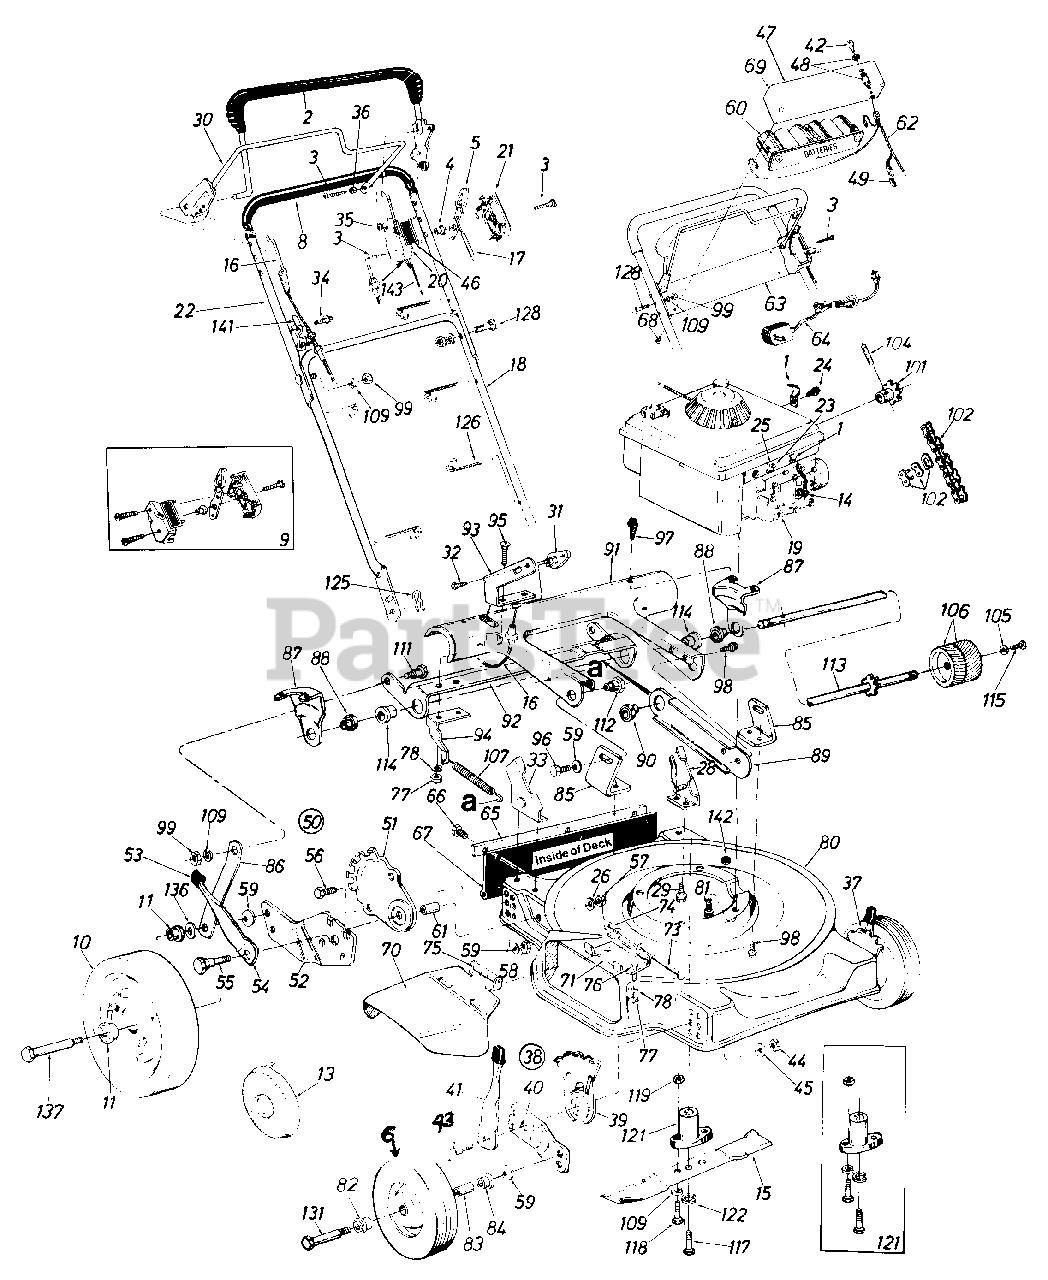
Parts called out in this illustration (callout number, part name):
1	Casing Clamp
2	Control Handle Ass'y.-L.H.
3	Truss Mach. Hi-B Tap Scr. #12 x 1.5"
4	Control Disc Pin
5	Throttle Control Lever
6	Front Wheel Ass'y. Comp.
9	Control Housing Comp.
10	Rear Wheel Ass'y. Comp.
11	Fl. Ball Brg 1/2" 1 D.
13	Hub Cap
14	Spark Plug Insulator
15	22" Blade
16	Clutch Cable w/Spring-33"
17	Throttle Wire-53"
18	Lower Handle
19	Engine
20	Clutch Panel Half
21	Control Panel Haif
22	Upper Handle
23	Hex B-Tap Scr. #10 x .62"
24	Hex B-Tap Scr. #10 x .38"
25	Casing Clamp
26	Bell-Wash. 5/16" I.D.
28	Handle Brkt. Ass'y-L.H.
29	Hex B-Tap Scr. 5/16-18 x .5"
30	S.P. Bail Ass'y.
31	Barrel Cable Hold-Down R.H.
32	B-Tap Scr. #10 x .44 Lg.
33	Handle Brkt. Ass'y-R.H.
34	Hex Wash. AB-Tap Scr. 5/16 x .75"
35	Spr-Wash. .206 I.D. x .448
36	Spacer .23 I.D. x .30 O.D.
37	Front Height Adj. Ass'y.-L.H.
38	Front Height Adj. Ass'y.-R.H.
39	Height Adj. Plate
40	Pivot Bar
41	Spring Lever Ass'y. w/Knob
42	Ignition Key
43	Shld. Bolt .50 Dia. x .430
44	Hex Nut 3/8-16 Thd.
45	Bell-Wash. .39 I.D. x 1.38 O.D.
46	Control Label
47	Instruction Label
48	Ignition Switch
49	Plug
50	Rear Height Adj. Ass'y.-R.H.
51	Index Plate
52	Pivot Bar-R.H.
53	Spring Lever Knob
54	Spring Lever
55	Shld. Bolt .50 Dia. x .433
56	Hex Bolt 3/8-16 x .75
57	Hex Cent. L-Nut 5/16-18 Thd.
58	Hex Nut 3/8-16 Thd.
59	Bell-Wash. .40 I.D. x .88 O.D
60	Battery Pack
61	Spacer .383 I.D. x .503 O.D.
62	Wire Harness
63	Lower Battery Tray
64	Battery Charger
65	Retaining Strip
66	Hex AB-Tap Scr. 1/4 x .62
67	Rear Flap Ass'y.
68	Truss Mach. Hi-Riser Tap Scr. 1" Lg.
69	Battery Tray
70	Chute Deflector Ass'y.
71	Adapter Plate
73	Pivot Pin
74	Push Nut 1/4"
75	Torsion Spring
76	Hex Bolt 1/4-20 x .50 Lg.*
77	Hex Nut 1/4-20 Thd.
78	L-Wash. 1/4 I.D.
80	22" Deck Ass'y
81	Hex TT-Tap Scr. 3/8-16 x 1.0
82	Ball Bearing 3/8" I.D.
83	Spacer
84	Ball Bearing 1/2" I.D.
85	Pivot Brkt.
86	Link
87	Axle Brkt.
88	Fl. Ball Brg. 1/2" I.D.
89	Brg. Support
90	Fl. Ball Brg. 1/2" I.D.
91	Pinion-Pivot Cover
92	Drive Engagement Cam
93	Engagement Arm-L.H.
94	Spring Bracket
95	Carriage Bolt lh-20 x .62
96	Hex Bolt 3/8-16 x .50 Lg.
97	Hex AB-Tap Scr. 1/4 x .62
98	Hex AB-Tap 1/4 x .62"
99	Hex Nut 5/16-18 Thd.
101	1OT Sprocket Ass'y.
102	#48 Chain 1/2" Pitch 50 Links
104	Spring Pin Spir. 3/16 Dia. x 1.0
105	Bell-Wash..265" I.D.
106	Drive Pinion Half
107	Extension Spring 4.25 Lg.
109	L-Wash. 5/16 I.D.
111	Shld. Bolt .437 Dia. x .162
112	Shld. Nut .625 Dia. x .165
113	Pinion Shaft w/7T Sprocket
114	Fl. Ball Brg. .501 I.D. H.D.
115	Hex TT-Tap Scr. 1/4-20 x .501' Lg.
117	Hex Bolt 3/8-24 x 2.25
118	Hex Bolt 5/16-24 x 1.0-Spec.
119	Hex Nut 5/16-24 Thd.
121	Blade Adapter Kit
122	L-Wash. 3/8 I.D.-H.D.
125	Intern. Cot. Pin 5/16 Dia.
126	Cable Tie
128	Curved Carriage Bolt 5/16-18 x 1.38" Lg.
131	Front Axle Bolt
136	Fl-Wash. .531 I.D. x .93 O.D.
137	Rear Axle Bolt
141	Cable Brkt.
142	Plastic Plug
143	Control Cable-39" (Green)
